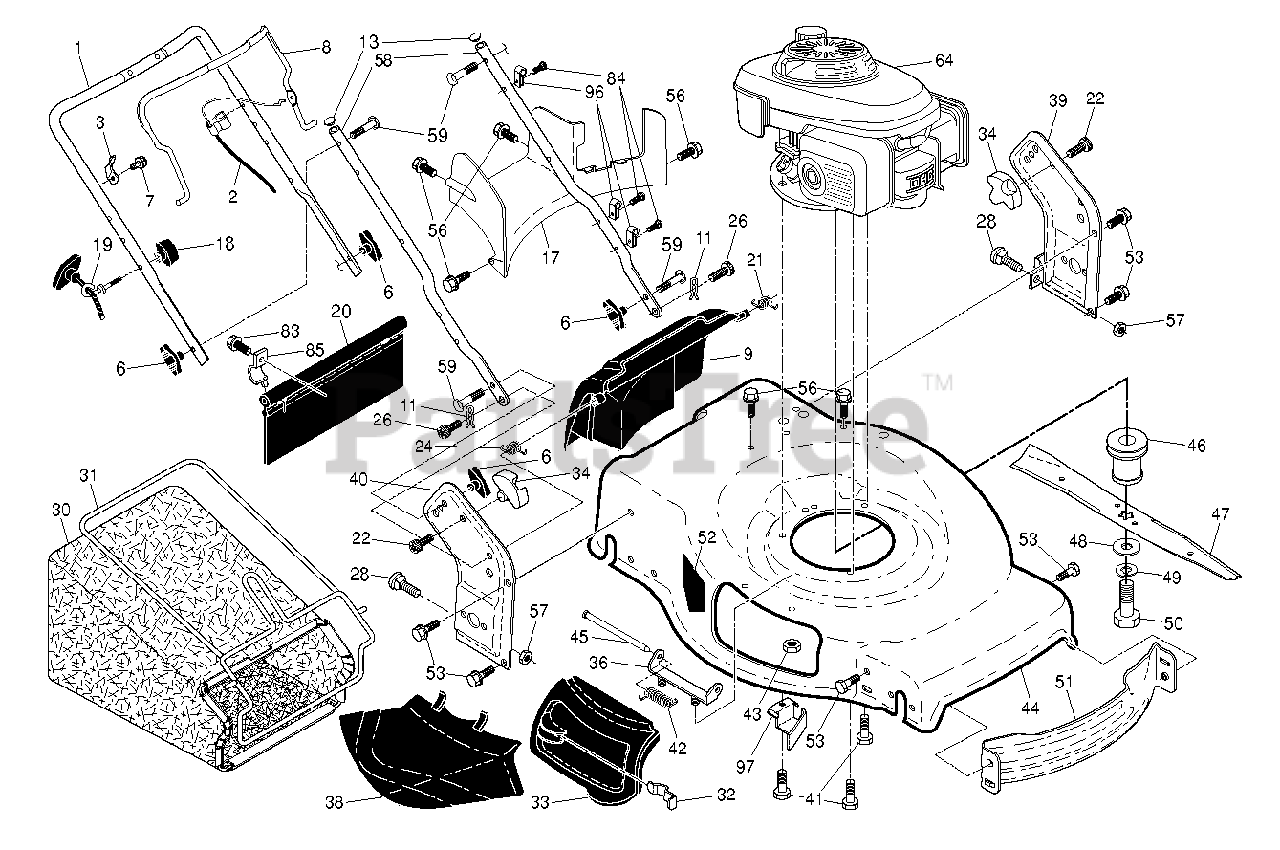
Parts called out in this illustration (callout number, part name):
1	HANDLE.UP.DSTR.EZ.FG/RGD.CREAS
2	CABLE.MZR.ZONE.CONTROL
3	BRACKET.UPSTOP.RT
8	BAIL.MZR.EZ2.DSTRT.22+.421
9	DOOR.REAR.22PLUS.MB.RWD.SAFETY
11	COTTER.HAIRPIN.DOOR/HANDLE.PIV
13	PLUG.PLASTIC.7/8".14-20.GAUGE
17	BAFFLE.REAR.22+RGD.AWD.PLASTIC
18	T-KNOB.NEW ROPE GUIDE
19	Rope Guide, Blk Zinc Chrom
20	SKIRT.REAR.22PLUS.RGD.LW.2012
21	SPRING.LH.GRAY
22	SCREW.PAN.HEAD.#10
24	SPRING.RH.GRAY
26	SCREW,DOOR/HANDLE.PIVOT
30	GBAG.A1640416S.BLK.PPRO.MRG.
31	Grass Bag Frame, 22+ Black
32	LATCH.DOOR.ZINC
33	DOOR.MULCH.22.BLACK.MULTI-BRAN
34	BRACKET.GRASSBAG.ATTACHING.BLK
36	BRACKET.ASM.HINGE.21.FWGD.
38	DEFLECTOR.CLIPPING.22.BLACK
39	Handle Bracket Assembly, LH 22+ Black
40	Handle Bracket Assembly, RH 22+ Black
41	BOLT 3/8-16X1-1/8
42	SPRING.TORSION
43	NUT.HEX.FLANGE.1/4
44	KIT.HSG.22+.RGD.MC.M421.TRI
45	ROD.HINGE.21
46	ADAPTER.BLADE.25MM.3MPH
47	BLADE.22+.PREMIUM/PREC.FGD/RGD
48	WASHER,HARDEN
50	SCREW, HEX HD 3/8-24 X 1-3/8
51	BAFFLE.FRONT.22.PLUS
52	No Step Decal
53	BOLT.5/16HEX.WHS.HD
56	SCREW.HX.13X.750
57	NUT.FLANGE.5/16
58	HANDLE.LOWER.22+BT.2PC.BLK
59	BOLT, HANDLE 5/16-18X1.75
83	TAPPING SCREW
84	FASTENER.PUSH.O.250X0.783
85	BRACKET.SKIRT.22+.BZP
96	CLIP.CABLE.BLK
97	BRACKET.BELT.GUIDE.22+.BZP
